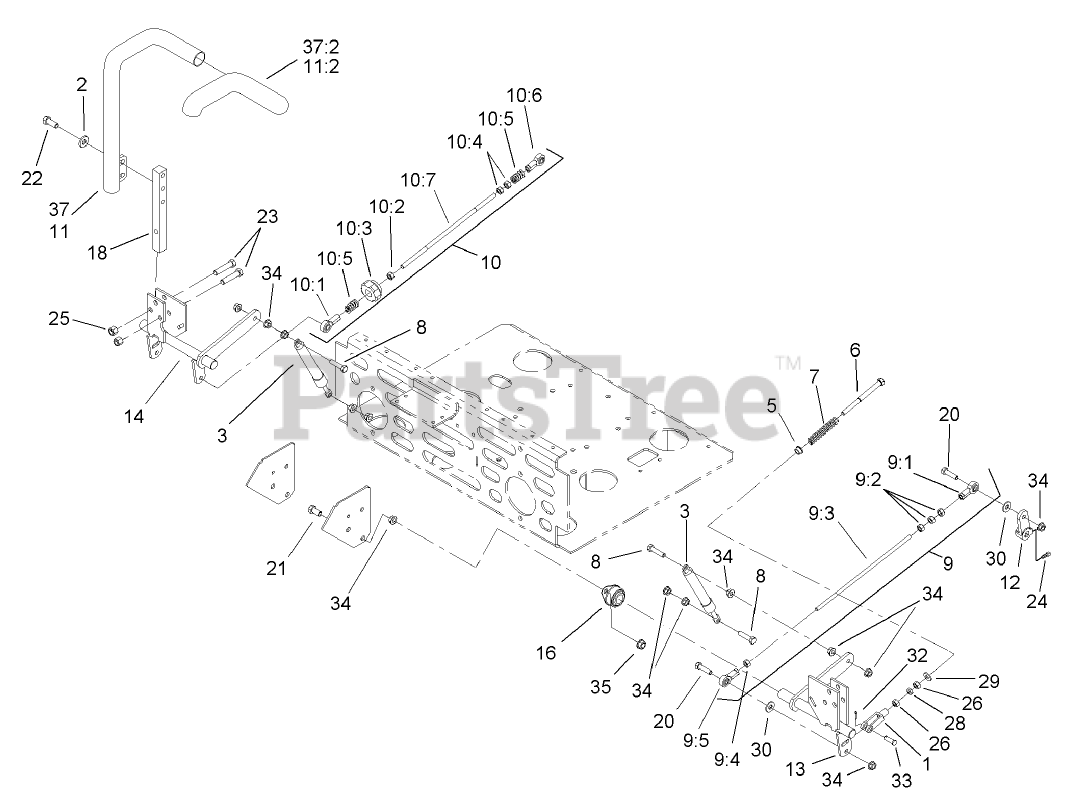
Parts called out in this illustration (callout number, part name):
1	YOKE-ADJUSTABLE
2	WASHER-BELLEVILLE
3	DAMPER-CONTROL, MOTION
5	BUSHING-FLANGED
6	BOLT-RETURN, NEUTRAL
7	SPRING-RETURN, NEUTRAL
8	SCREW-HH
9	Tracking Rod ASM
9:1	BALLJOINT-RH
9:2	NUT-HEX
9:3	Link-Rod, Tracking
9:5	BALLJOINT-LH
10	Tracking Rod ASM
10:1	BALLJOINT-RH
10:2	NUT-HEX
10:3	KNOB-TRACKING
10:5	SPRING-COMPRESSION
10:6	BALLJOINT-LH
10:7	Link-Rod, Tracking
11	LH Lever ASM
11:2	Grip-Control, Motion
12	ARM-CONTROL, PUMP
13	Control-Motion, LH
14	Control-Motion, RH
16	BEARING-FLANGE, SIDE
18	ARM-SHAFT, CONTROL
20	SCREW-HH
21	SCREW-HH
22	SCREW-HH
23	SCREW-HH
24	SCREW-SET
25	NUT-LOCK, NI
26	NUT-HEX
28	NUT-JAM
29	WASHER-FLAT
30	WASHER-FLAT
32	PIN-COTTER
33	PIN-CLEVIS
34	NUT-HF
35	NUT-HHF, WHIZ
37	RH Lever ASM
37:2	Grip-Control, Motion
